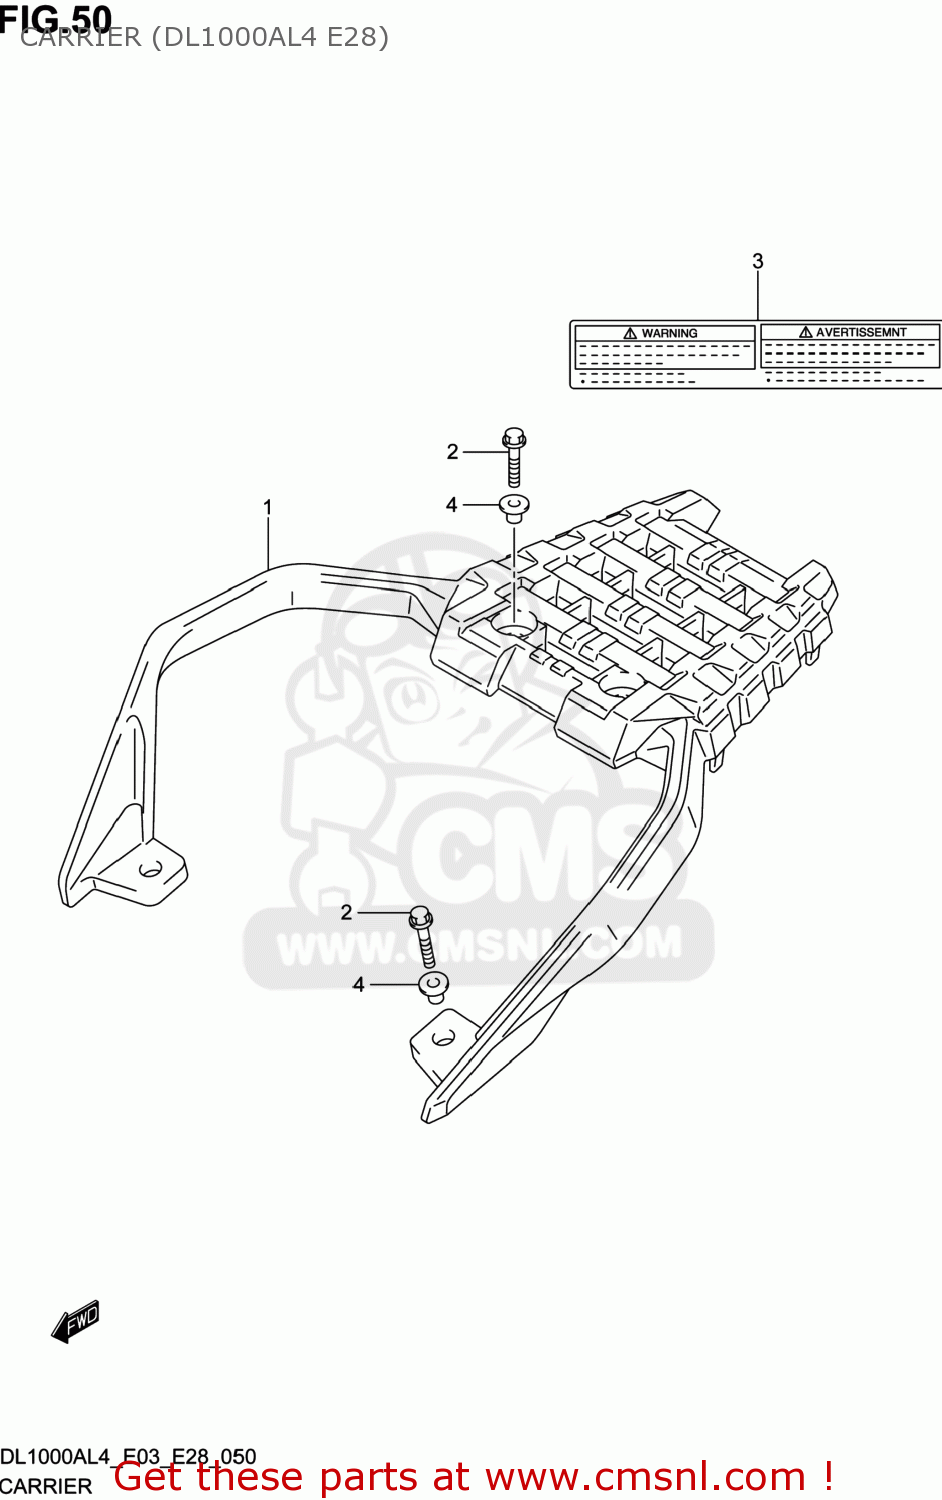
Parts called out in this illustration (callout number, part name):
1	CARRIER,SPORT(SILVER)
2	BOLT(8X35)
3	LABEL,WARNING LUGGAGE CARRIER
4	WASHER
